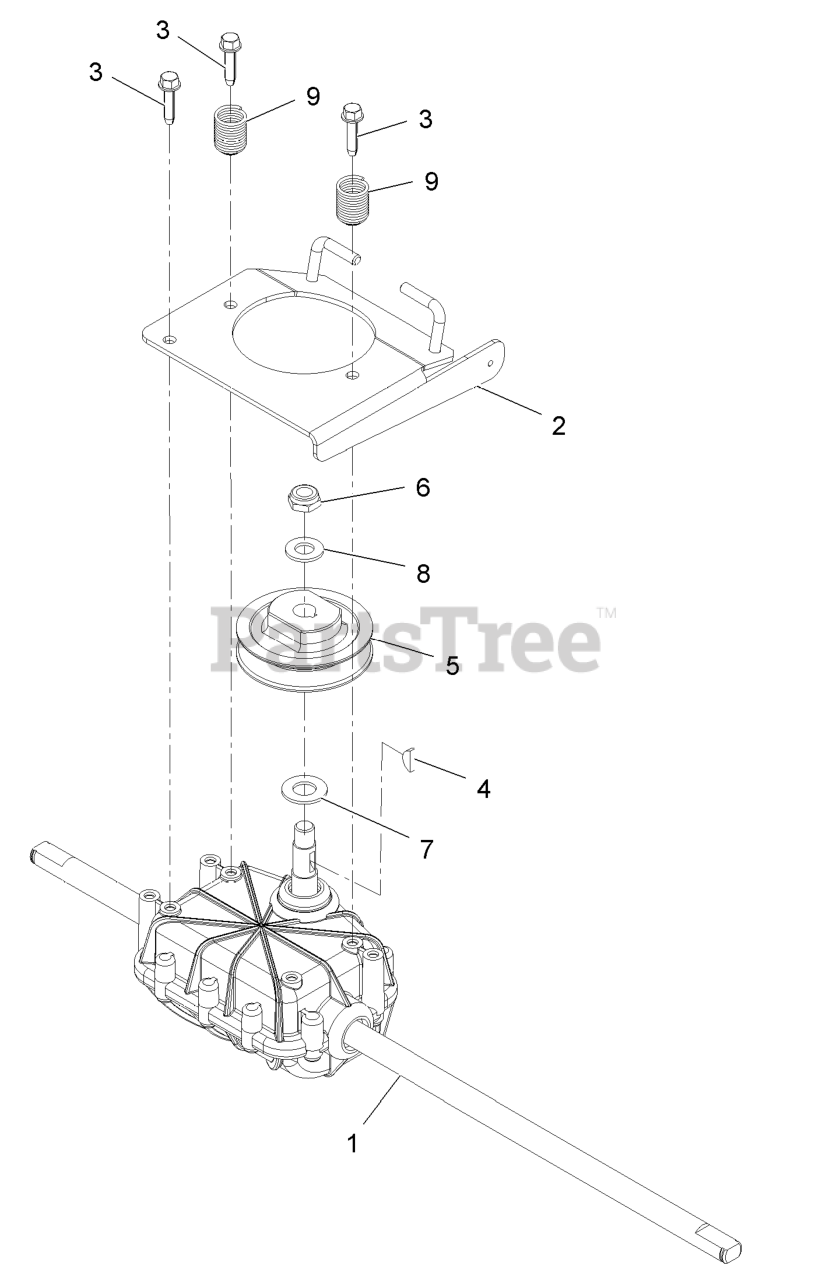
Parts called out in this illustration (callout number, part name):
2	TRANSMISSION PLATE ASM
3	SCREW-SPECIAL
4	KEY-WOODRUFF
6	NUT-HEX
7	WASHER-THRUST
8	WASHER-FLAT
9	SPRING,COMPRESSION
